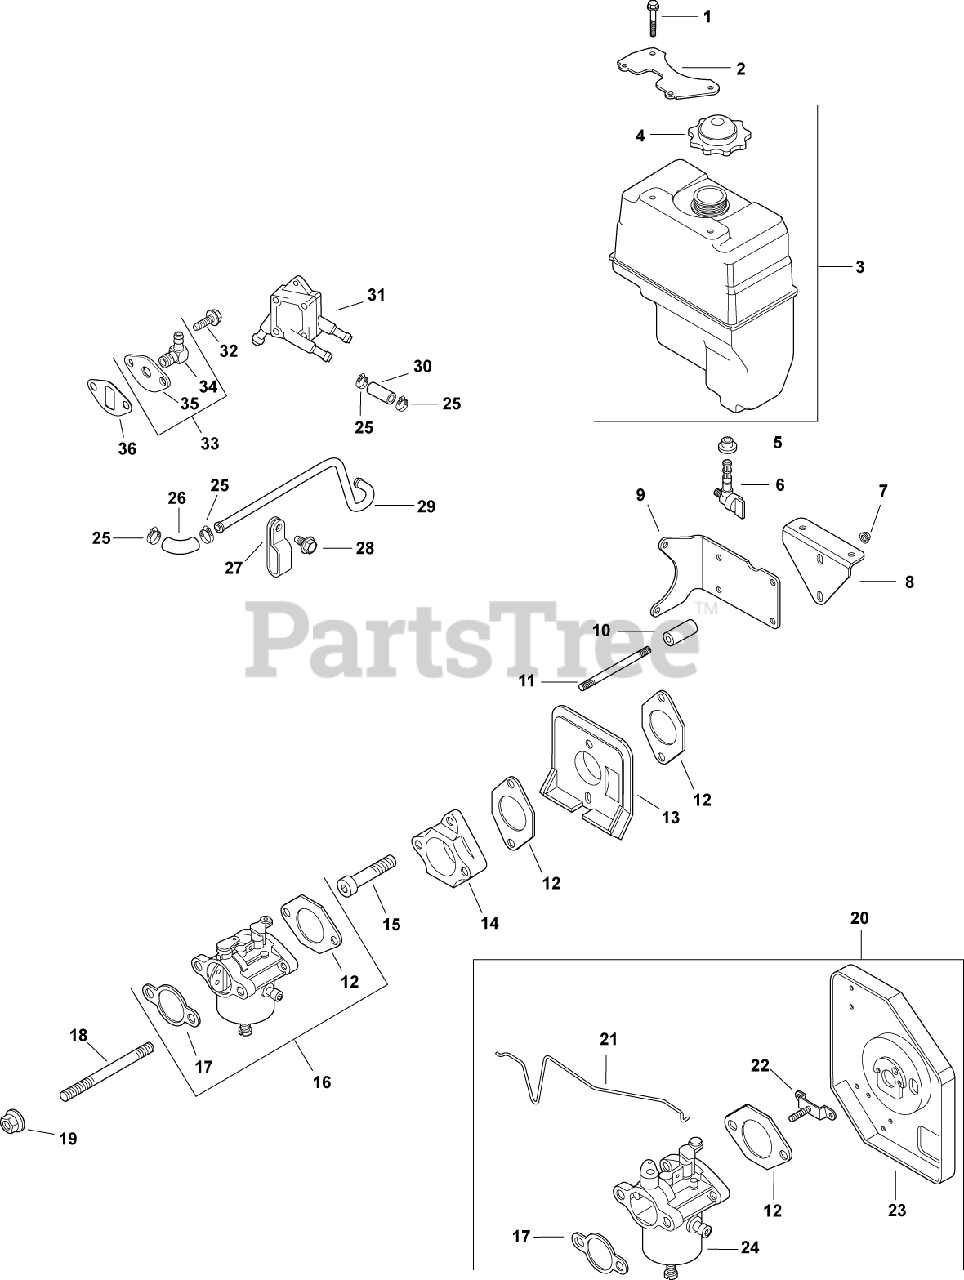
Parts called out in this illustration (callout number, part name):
1	SCREW,FLG THD FRM M6X1.0X25-(#25086395S)
2	BRACKET, FUEL TANK
3	KIT, FUEL TANK
4	CAP, FUEL TANK
5	BUSHING, FUEL TANK
6	VALVE, FUEL SHUT-OFF
7	NUT, FLG M8X1.25
9	BRACKET, FUEL TANK
10	SPACER, FUEL TANK
11	STUD, M8X1.25X133-USE 25 755 54-S
12	GASKET, CARBURETOR
13	DEFLECTOR, HEAT
14	ADAPTER, CARBURETOR
15	SCREW, SKT CAP M6X1.0X35
16	KIT, CARBURETOR w/GASKETS
17	GASKET, AIR CLEANER BASE
18	STUD,M6X1.0X116
19	NUT, FLG M6X1.0
20	KIT, CARB. RETROFIT
21	LINKAGE, CHOKE
22	BRACKET, AIR CLEANER
23	BASE, AIR CLEANER
24	CARBURETOR W/GASEKTS - USE 12 853 139-S
25	CLAMP, HOSE (KM)-USE 25 237 31-S
26	HOSE, FUEL LOW-PERMEATION
27	CLIP, TUBE & WIRING (KM)
28	SCREW, FLG THD FRM M5X.8X10
29	LINE, FUEL - DISCONTINUED
30	LINE - DISCONTINUED
31	PUMP, FUEL
32	SCREW,FLG THD FRM M6X1.0X20-(#25086396S)
33	COVER,FUEL PUMP ASSEM - DISC.
34	CONNECTOR, 90 DEG. HOSE
35	COVER, FUEL PUMP PAD - DISCONTINUED
36	GASKET, FUEL PUMP
